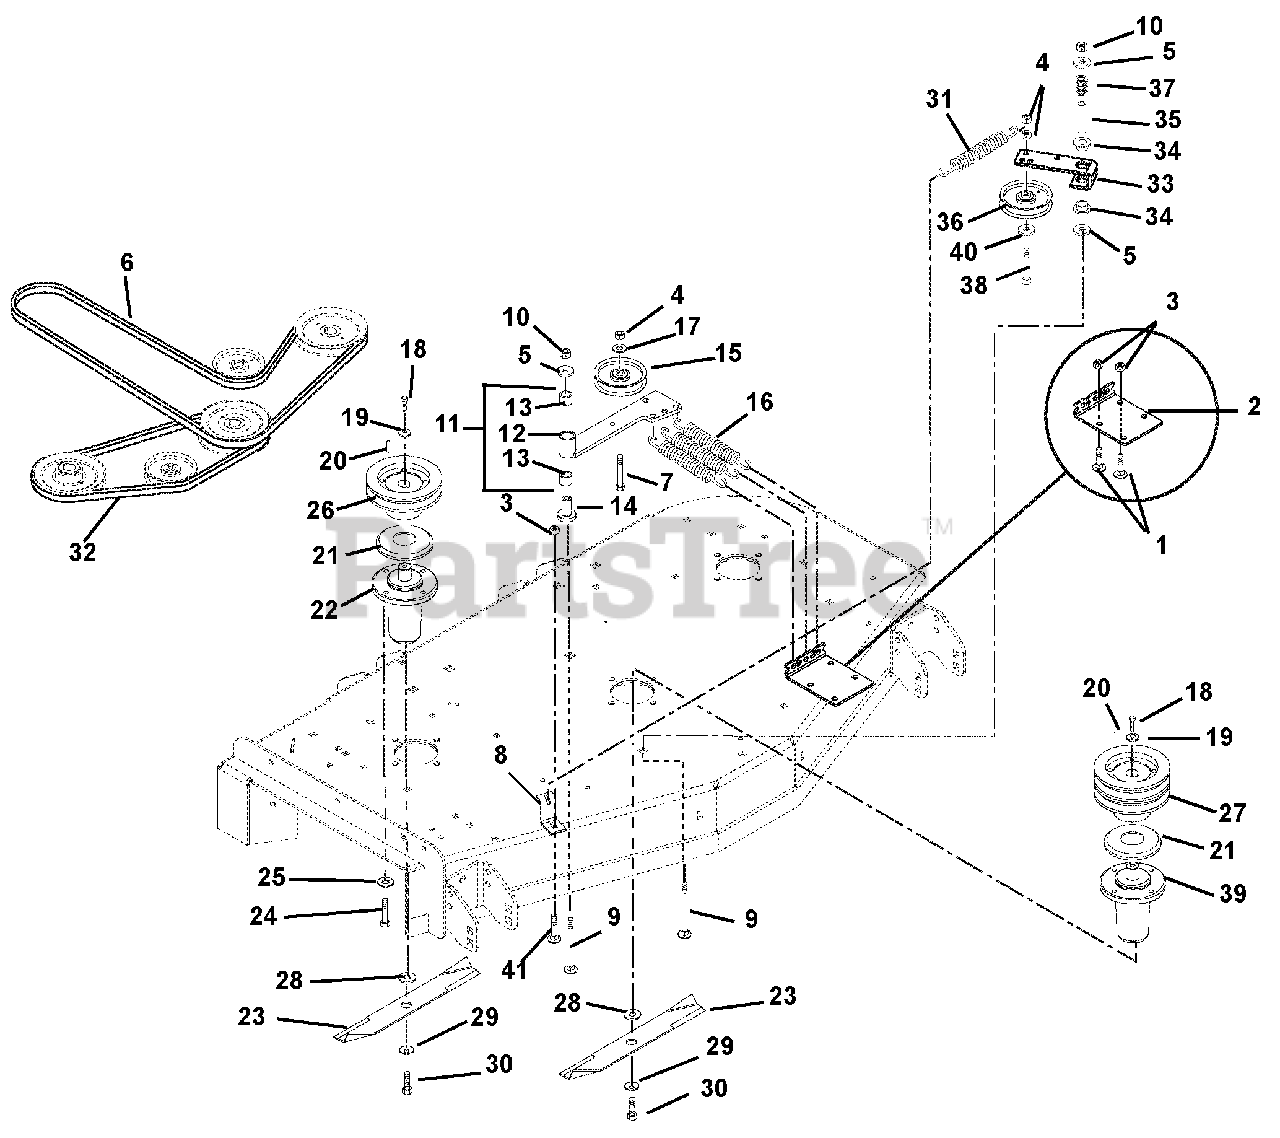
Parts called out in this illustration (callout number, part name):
1	Bolt, Round Head Square Neck .38-16 x .75 Grade 5
2	Bracket, Spring
3	Nut, Locking Top Flange .38-16
4	Nut, Locking Center .38-16
5	Washer, Flat Steel .531 x 1.25 x .10
6	V-Belt, B-Section 54.06 x .625
7	Bolt-Round Head Square Neck .38-16 x 2.75 Grade 5
8	Anchor, Spring
9	Bolt, Round Head Square Neck .50-13 x 3.50 Grade 5
10	Nut, Locking Top Flange .50-13
11	Assembly-Deck Idler Pivot Arm (Contains Items 12 & 13)
12	Weldment, Deck Idler Pivot Arm
13	Bearing, 1.00 x 1.12 x .75
14	Bearing, Pedestal Powdered Metal
15	Idler, Flat 4.00 x .38 (2.32W)
16	Spring, Extension
17	Washer, Flat Steel .375 x 1.125 x .065
18	Bolt, Hex .38-16 x 1.00 Grade 8
19	Washer, Cupped Serrated .375
20	Key, Square .25 x .25 x 1.00
21	Slinger, Dust
22	Assembly, Maintenance Free Spindle
23	Blade 60" Mower CE
24	Bolt, Hex .38-16 x 1.00 Grade 5
25	Washer, Locking .38 x .094 Regular
26	Weldment, Spindle Sheave 6.00
27	Sheave, Double (6.25)
28	Washer, Flat .64 x 1.81 x .25
29	Washer, Bellville .63 x 1.625 x .14
30	Bolt, Hex .62-18 x 1.75 Grade 8
31	Spring, Extension (316, 317)
32	V-Belt B-Section 23.94 x .625
33	Arm, Idler Pivot
34	Bushing, Flange .762 x 1.00 x .58 x 1.48 Nylon
35	Spacer .56 x .75 x 2.44 Steel
36	V-Idler, 4.00 x .38
37	Spring, Compression .085 x .80 x 1.00
38	Bolt, Hex .38-16 x 2.25 Grade 5
39	Spindle Assembly (Center)
40	Washer, Flat Steel .406 x .812 x .05
41	Bolt, Round Head Square Neck .38-16 x 1.00 Grade 5
